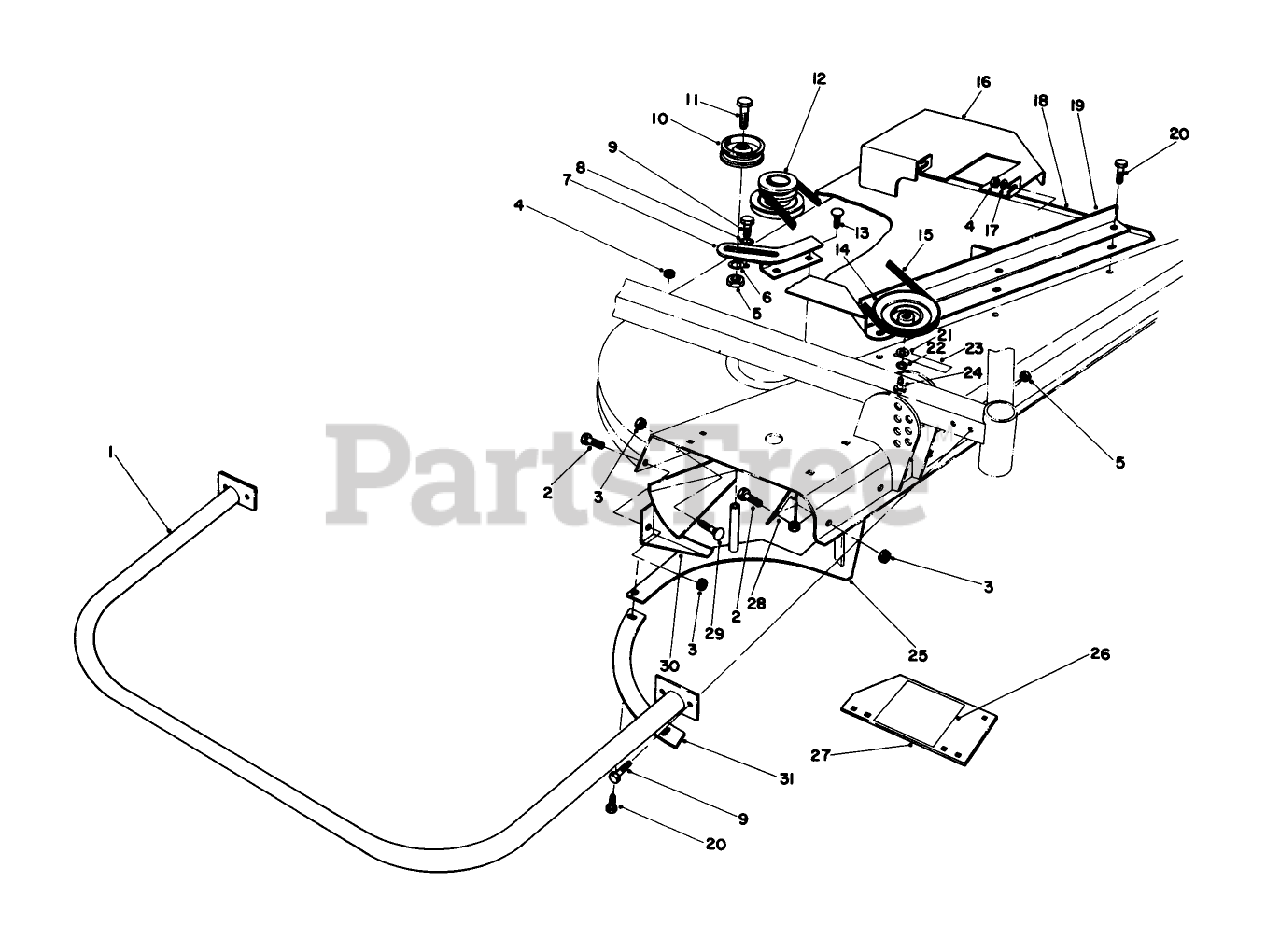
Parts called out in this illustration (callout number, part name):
1	Bumper
2	Screw
3	NUT-LOCK, CONE
5	NUT-LOCK, CONE
6	WASHER-FLAT
7	IDLER BRKT R
8	WASHER-LOCK
9	SCREW-HH
10	IDLER PULLEY R
11	SCREW-HH
12	PULLEY WA RO
13	BOLT-CARR
14	PULLEY WA BO
15	V-BELT
16	Cover Blower Drive
17	WASHER-FLAT
18	Cover-Right
19	Spring Bracket
20	SCREW-HH
21	Washer
22	WASHER-LOCK
23	WARNING DECAL
24	1/4-20 X 5/8 CAPSCREW
25	Rear Shelf
26	Decal-Caution
27	Cover Plate (Incl. Ref. #26)
28	Front Deflector
29	BOLT-CARR
30	Deflector Rear
31	Shelf-RH
